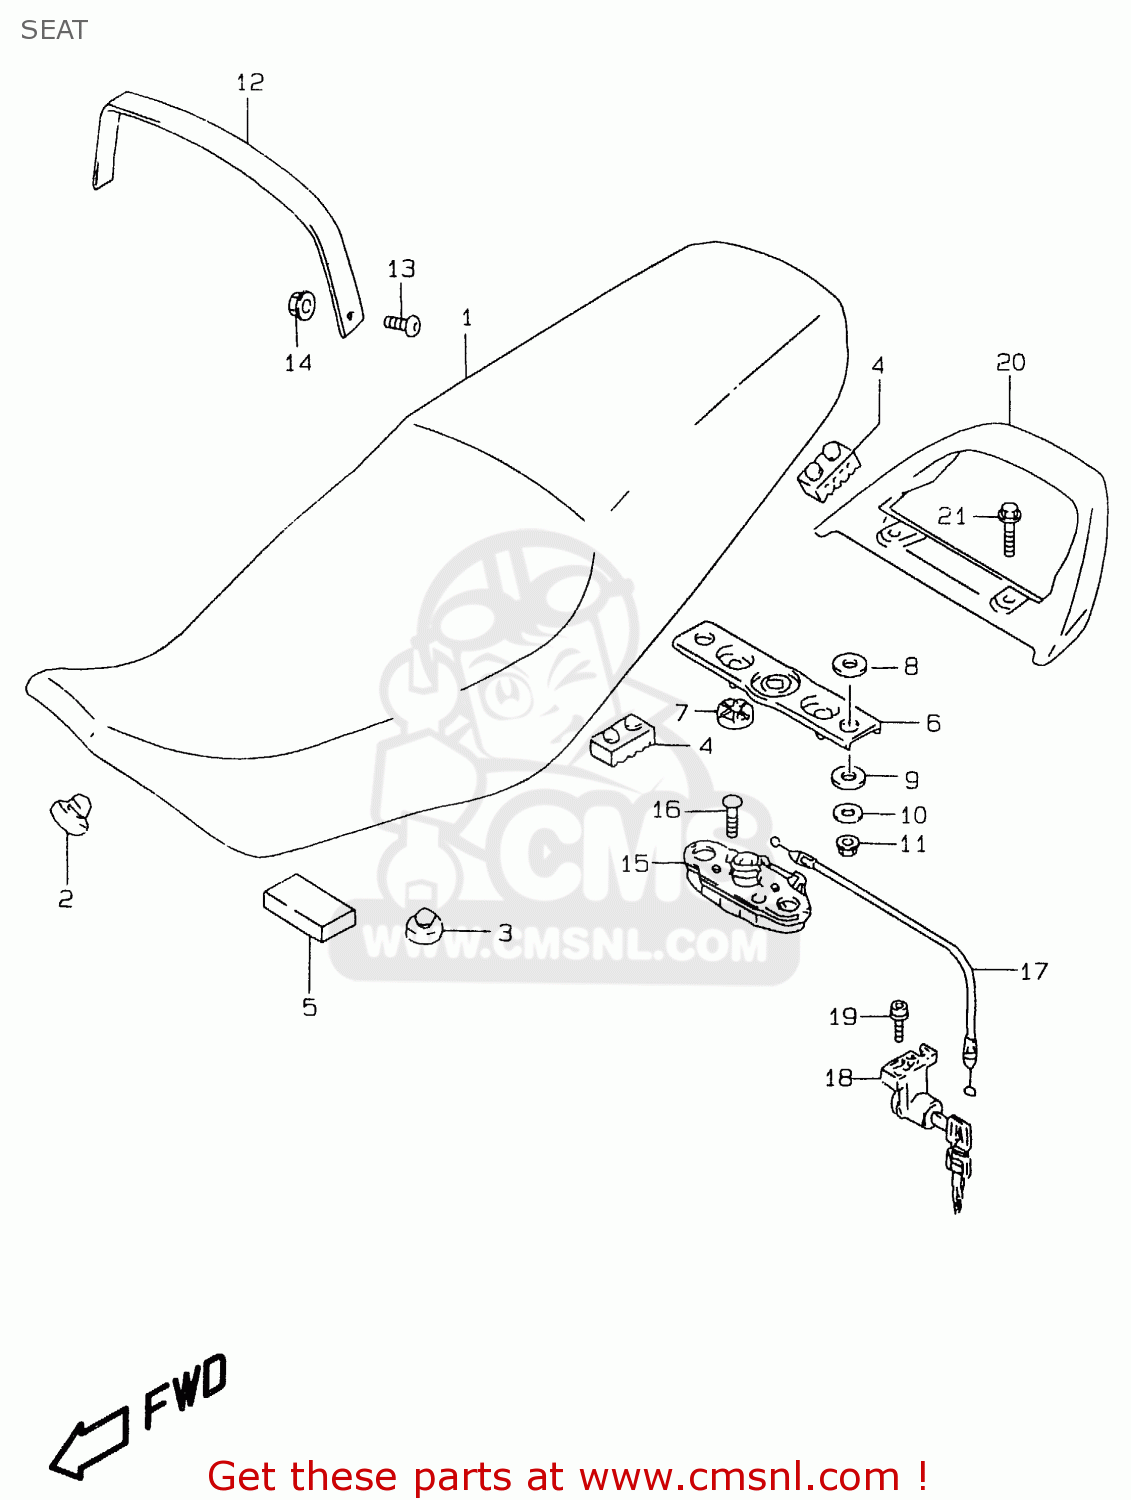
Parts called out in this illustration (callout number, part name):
1	SEAT SET
2	CUSHION
3	CUSHION
4	CUSHION,SEAT(40X20X15)
5	CUSHION(30X60X10)
6	STRIKER,SEAT LOCK
7	CUSHION,SEAT LOCK(10X22X6)
8	CUSHION,UPR
9	CUSHION,LWR
10	WASHER
11	NUT
12	BAND, SEAT (BLACK)
13	BOLT
14	NUT
15	LOCK ASSY,SEAT STRIKER
16	SCREW
17	CABLE,SEAT LOCK
18	LOCK SET,SEAT
19	SCREW
20	HANDLE,PILLION RIDER
21	BOLT
